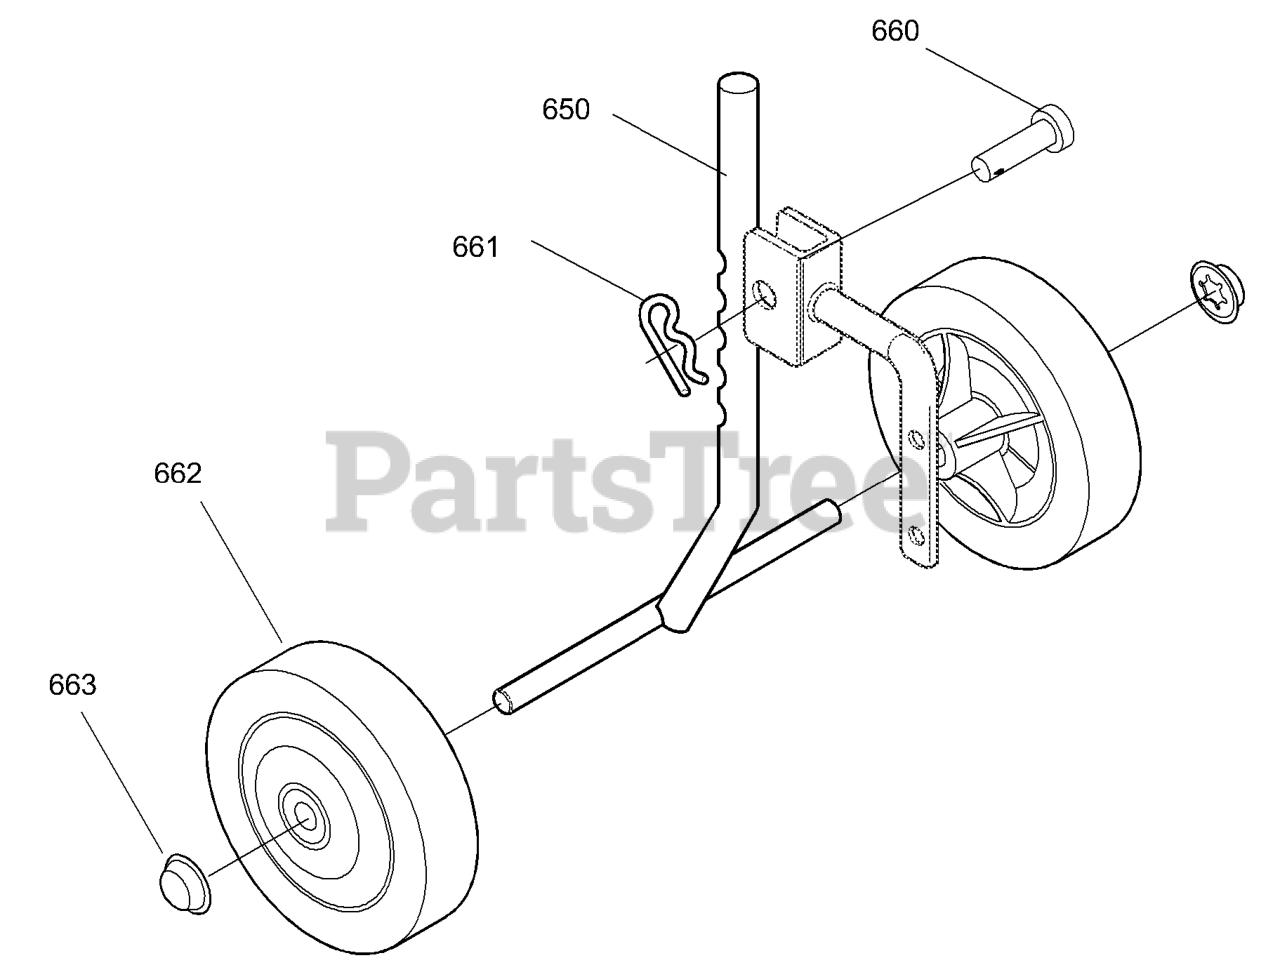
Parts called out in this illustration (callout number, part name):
650	Wheel Support Assy.
660	Clevis Pin
661	Hair Pin
662	Tire & Rim
663	Push On Nut
